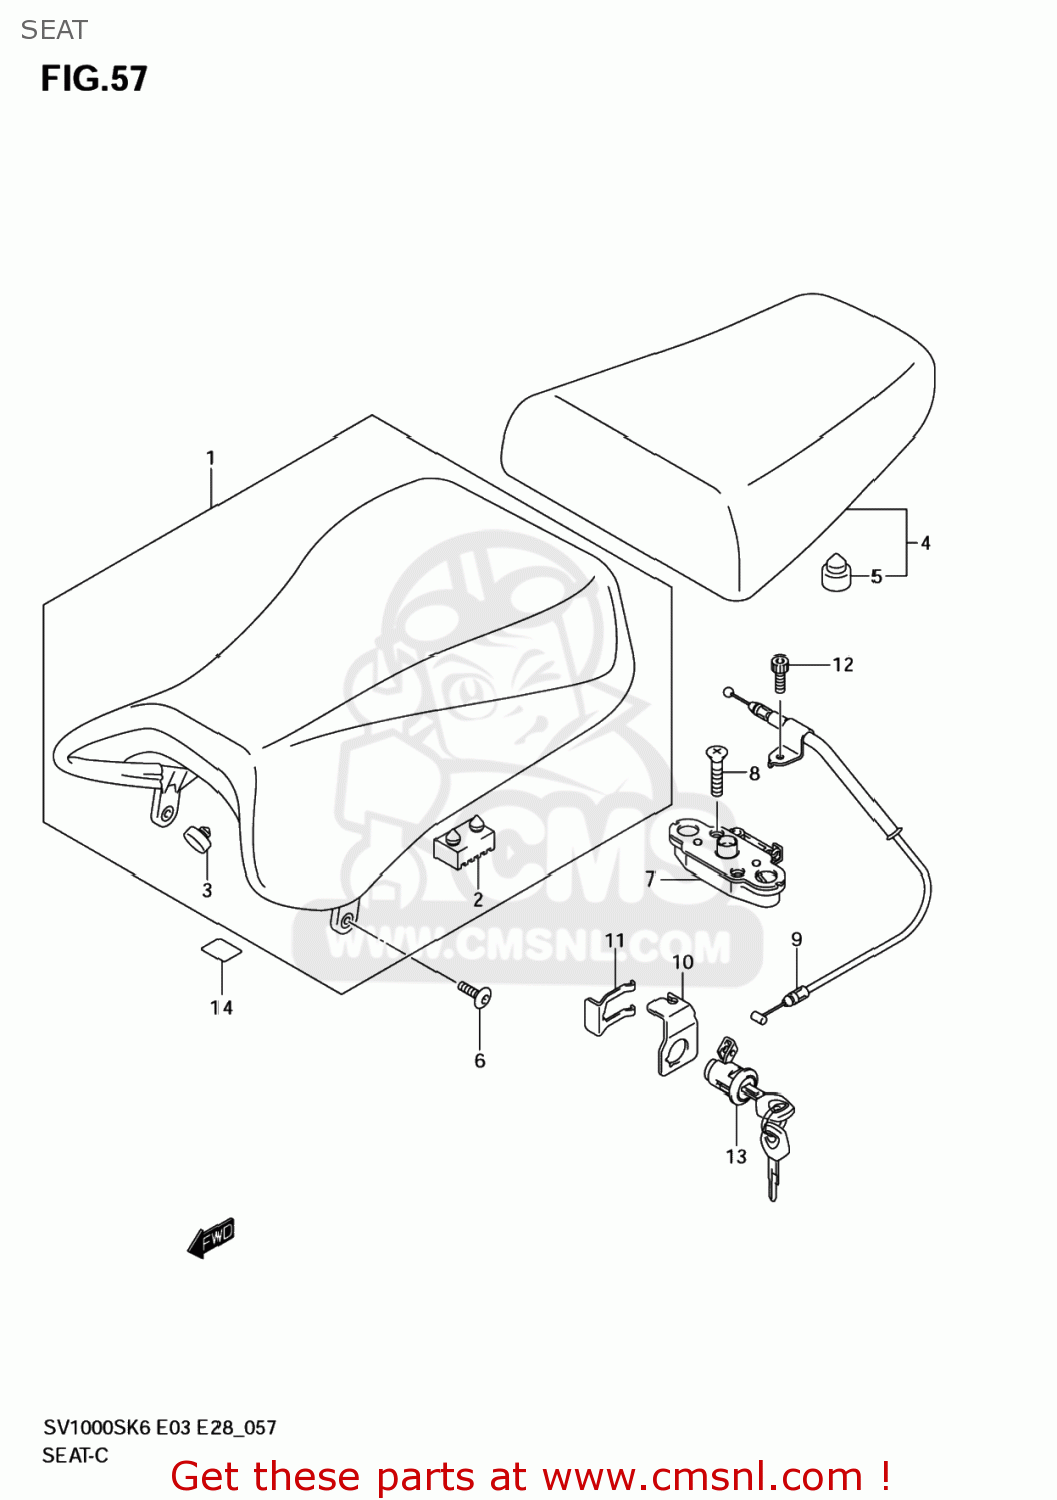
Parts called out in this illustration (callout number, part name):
1	SEAT ASSY(BLAC
2	CUSHION
3	CUSHION,FR
4	SEAT ASSY,PILLION
5	CUSHION
6	BOLT(6X18)
7	BRACKET,SEAT SUPPORT,RIGHT
8	SCREW
9	CABLE,SEAT LOCK
10	GUIDE,SEAT LOCK CABLE
11	PLATE,SEAT LOCK ASSY
12	BOLT
13	LOCK SET,SEAT
14	TAPE,FUEL TANK
